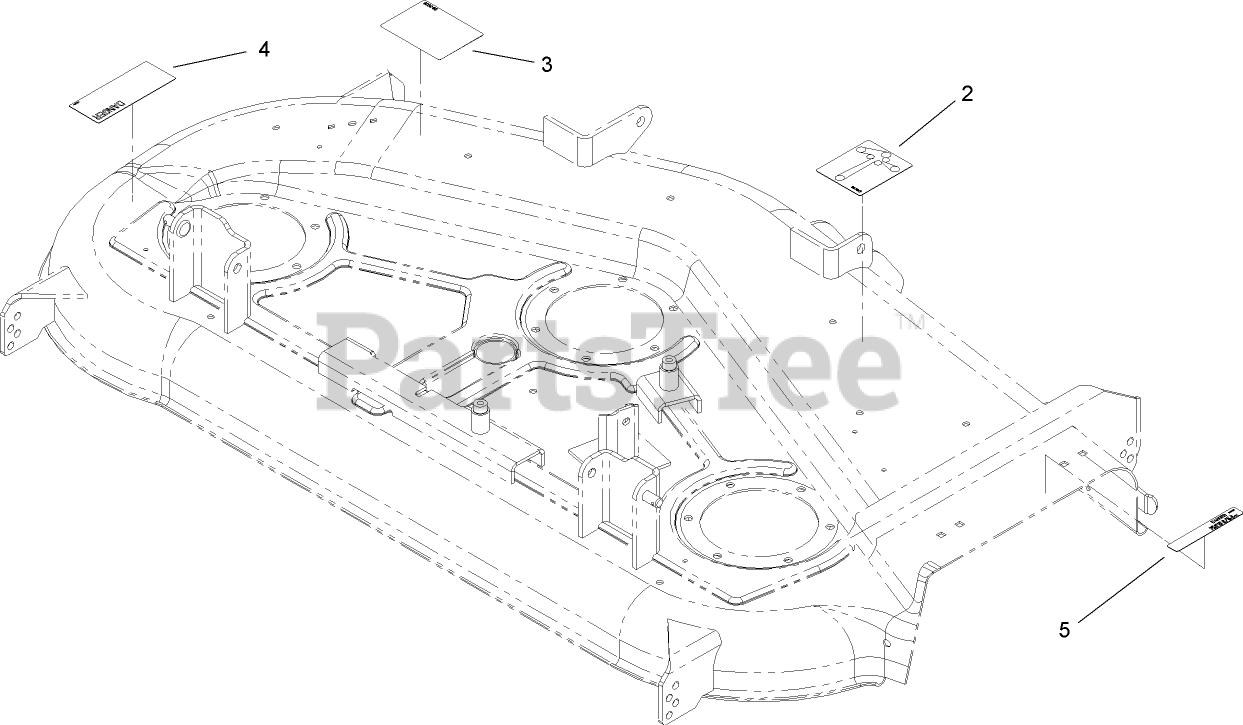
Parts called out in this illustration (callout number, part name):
2	DECAL-ROUTING, BELT
3	DECAL-ANTI SCALP
4	DECAL-DANGER
5	DECAL-DANGER
